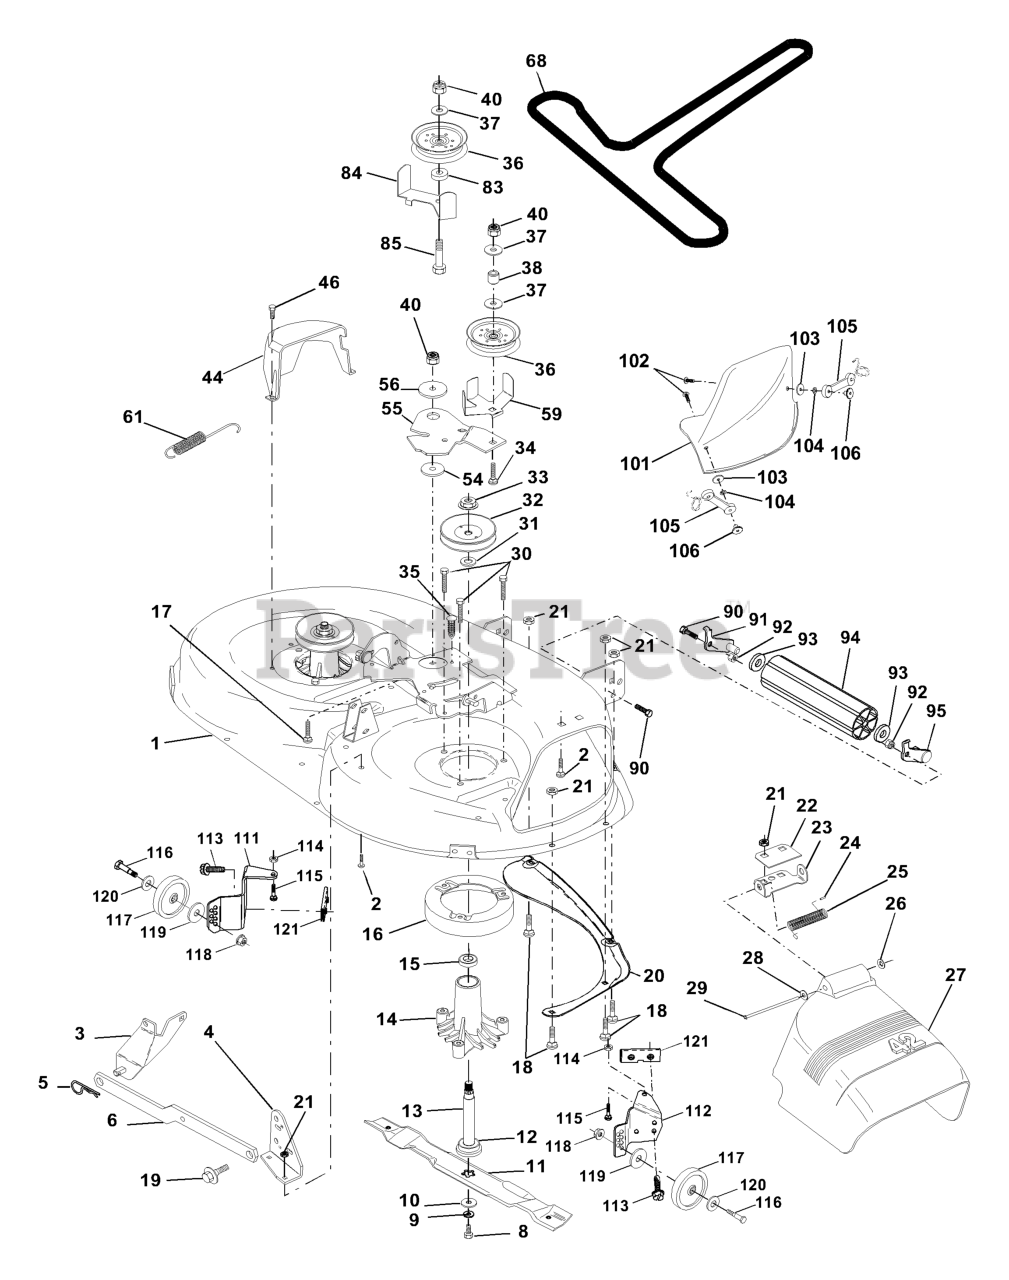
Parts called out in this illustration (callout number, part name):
1	DECK 42"
2	RP BOLT 5/16-18 X3/4 ZN/YEL GR
3	BRKT ASM SWAY BAR
4	BRKT DECK SW BAR
5	RETAINER-SPRNG RB
6	REAR SUSP ARM
7	NUT.71038.31-18.HEX.NYLOCK
8	BLADE BOLT
9	LOCKWASHER
10	WASHER.BLADE
11	BLADE.42".MULCH
12	BEARING.BALL.#6204.(MANDREL)
13	SHAFT ASM VENT
14	HOUSING.MANDREL.VENTED (MACHD)
16	STRIPPER
17	BOLT
18	BOLT
19	BOLT SHD 5/16-18
20	BAFFLE
21	LOCKNUT
22	STIFFENER BRACKET
23	DEFLECTOR BRACKET
24	CAP-SLEEVE LT
25	SPRING TORSION
26	NUT PUSH M
27	SHIELD.DEFLECTOR.MOWER.42".BLK
28	Washer 11/32 X 5/8 X 16 Ga
29	ROD.HINGE
30	SCREW
31	WASHER
32	MANDREL PULLEY
33	NUT
35	FASTENER.XMAS.TREE
36	FLAT IDLER PULLEY
37	WASHER
38	IDLER SPRING SPACER
44	GUARD MANDREL LH BLACK
46	SCREW.1/4-20X5/8
54	HARDENED WASHER
55	IDLER ARM
56	SPACER RETAINER
59	GUARD, BELT
61	SPRING EXTENSION
68	V-BELT TRIPATH
84	KEEPER BELT
85	BOLT
90	BOLT
91	BRACKET LH (A)
92	NUT
93	Washer 17/32 X 7/8 X 16 Ga
94	NOSE ROLLER
95	BRACKET RH (B)
101	COVER MULCH 42"
102	SCREW
103	LOCKWASHER #10
105	LATCH ASSEMBLY
106	WELDNUT
111	BRACKET
112	BRACKET
113	SCREW.THDROL.5/16-18X3/4.TTY
114	NUT
115	BOLT.CARR.5/16-18X1/2
116	BOLT, SHOULDER
117	WHEEL.GAUGE.BLK.4.93
118	LOCKNUT
119	WASHER.5/16.FLAT.STE.STD.
120	Washer 17/32 x 15/16 x 12 Ga.
121	BRACKET.EXTRUDED.GAGE.WHEEL
